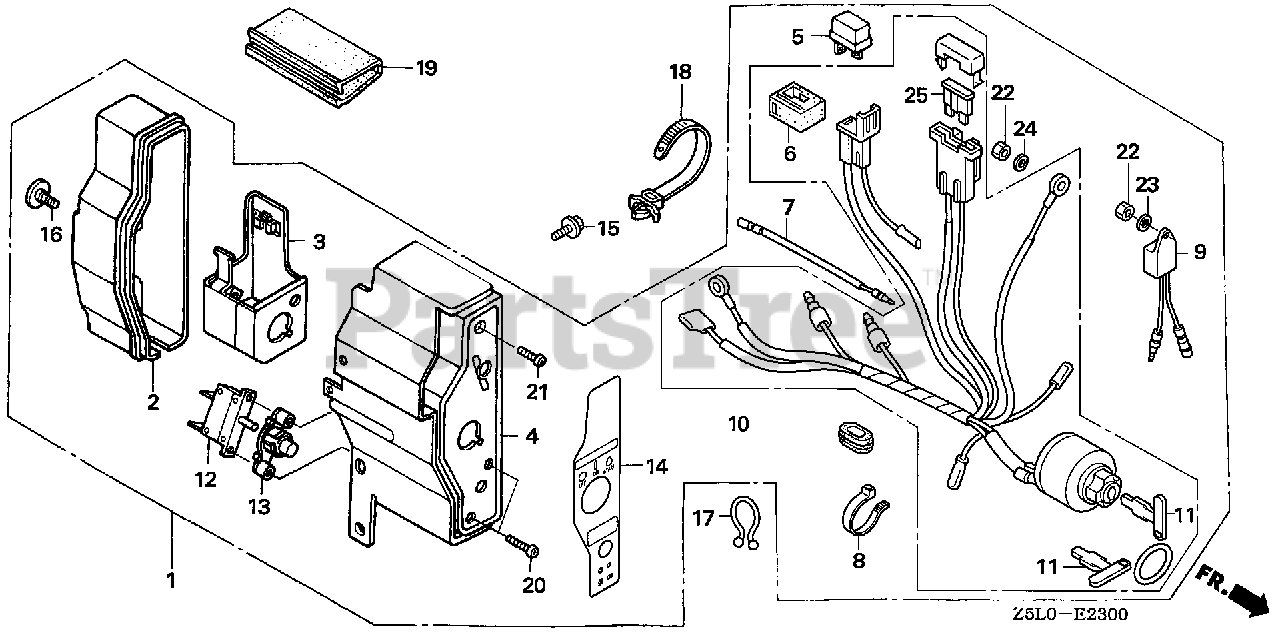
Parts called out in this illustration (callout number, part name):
1	BOX ASSY., CONTROL (3A) *NH1* (EXP-ALERT) (BLACK)
1	BOX ASSY., CONTROL (3A) *R280* (EXP-ALERT) (POWER RED)
2	CASE, CONTROL
3	BRACKET, CASE MOUNTING
4	PANEL, CONTROL *NH1* (BLACK)
4	PANEL, CONTROL *R280* (POWER RED)
5	RECTIFIER ASSY., SILICON (SHINDENGEN)
6	SUSPENSION, CONNECTOR
7	SUB-WIRE HARNESS
9	ALERT UNIT, OIL
10	SWITCH ASSY., COMBINATION (3A-CHARGE)
11	KEY (HONDALOCK)
12	PROTECTOR, CIRCUIT (3.5A)
13	LENS ASSY., PROTECTOR
14	MARK, CONTROL BOX (EXTERNAL)
15	BOLT, FLANGE (6X12) (CT200)
16	SCREW, SPECIAL (6X12)
17	CLIP, PURSE LOCK
18	STRAP, CABLE (118MM) (BLACK)
19	TUBE, FASTENER (30MM)
20	SCREW, PAN (3X12)
21	SCREW, PAN (4X12)
22	NUT, HEX. (4MM) (SOURCE: VINTAGE PARTS INC.)
23	WASHER, PLAIN (4MM)
24	WASHER, SPRING (4MM)
25	FUSE, BLADE (15A)
